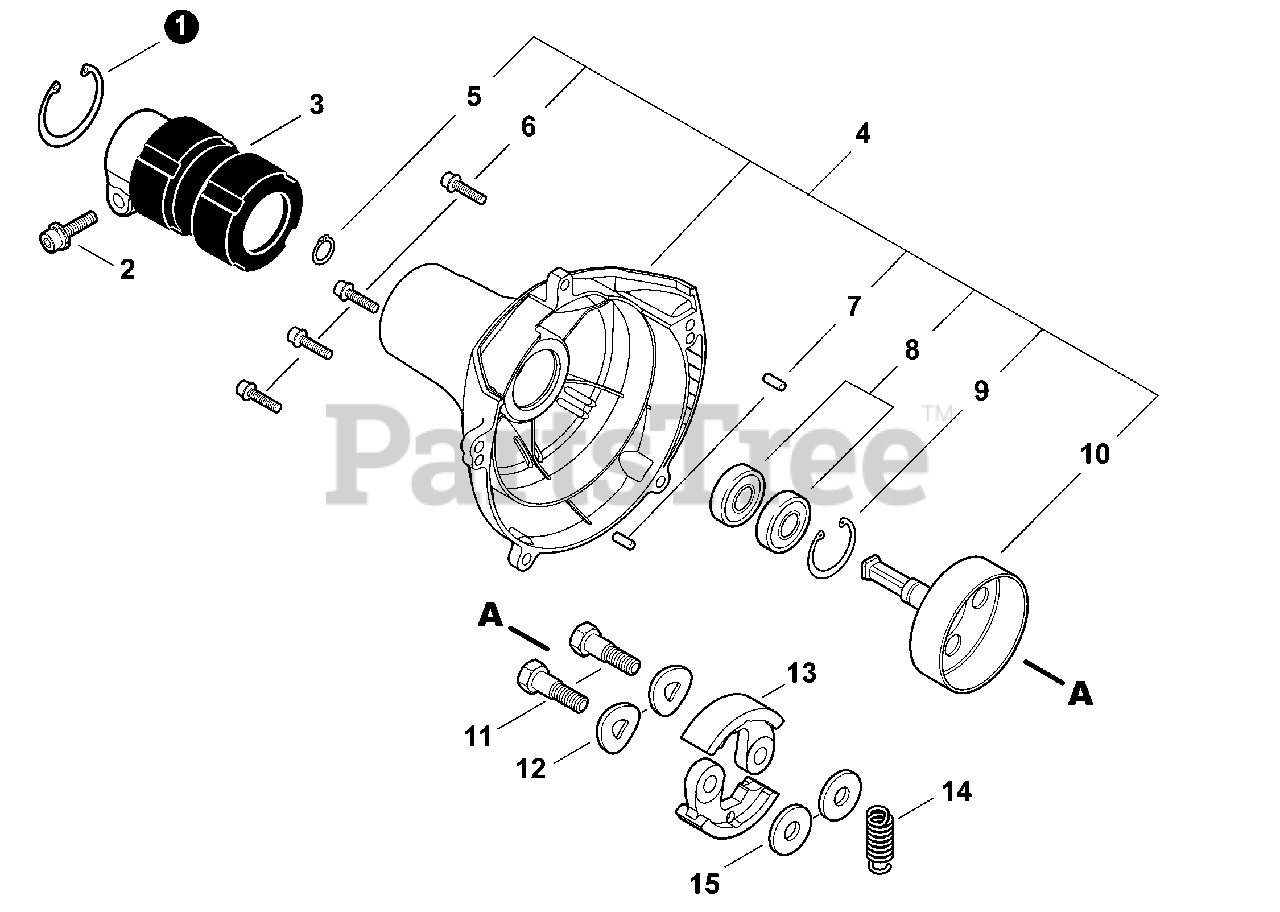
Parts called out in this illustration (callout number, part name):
1	CIRCLIP 42
2	BOLT, H.S. 5×28
3	HOLDER, MAIN PIPE
4	FAN CASE ASY
5	RING, RETAINING - 12
6	SCREW - 5×20
7	PIN, DOWEL
8	BEARING, BALL - 6001
9	RING, RETAINING - 28
10	DRUM, CLUTCH
11	BOLT, CLUTCH
12	WASHER - SPRING
13	SHOE, CLUTCH
14	SPRING, CLUTCH
15	WASHER - 6
